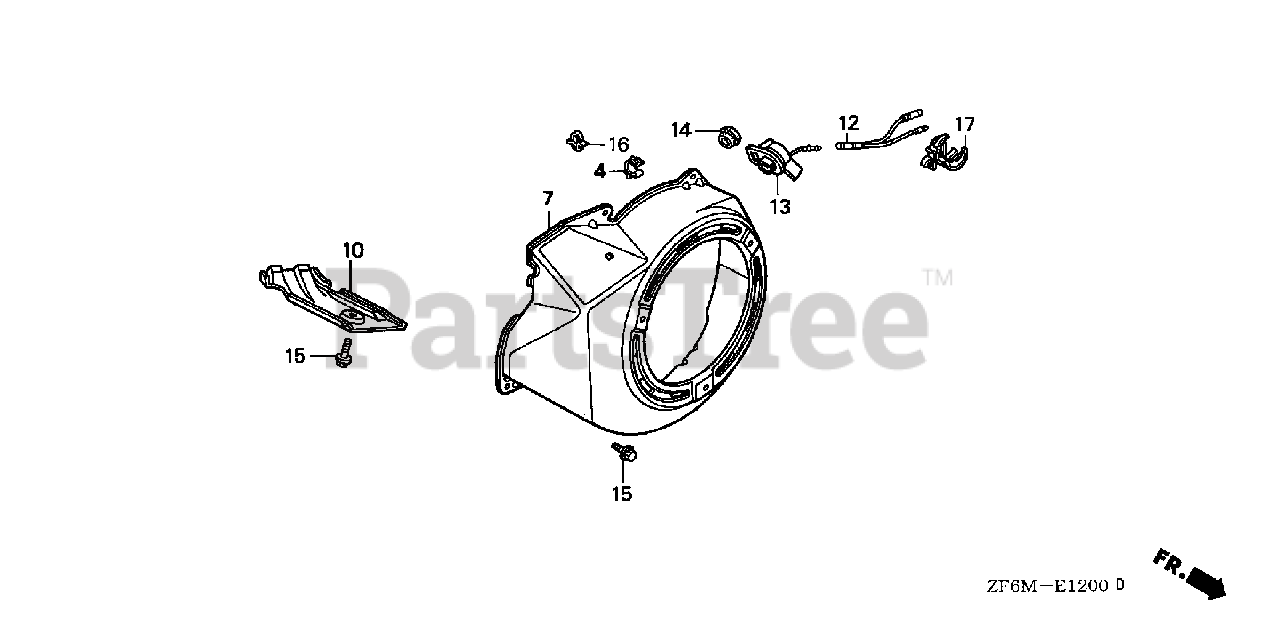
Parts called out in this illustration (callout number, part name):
4	CLIP, TUBE
7	COVER, FAN *R8* (BRIGHT RED)
10	SHROUD
13	SWITCH ASSY., ENGINE STOP
15	BOLT, FLANGE (6X12) (CT200)
